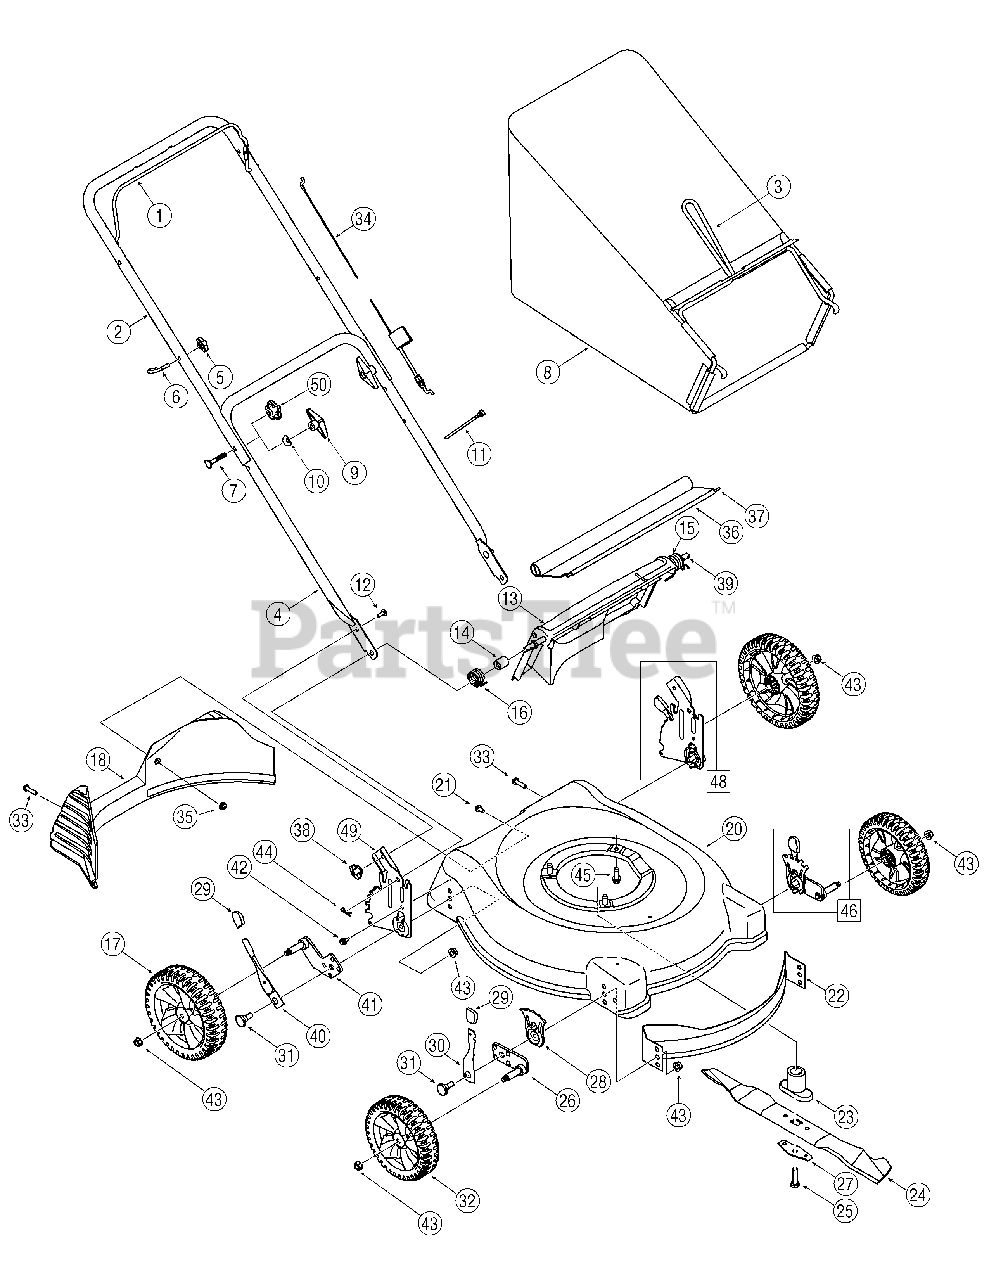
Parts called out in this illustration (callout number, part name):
5	Knob 1/4-20
6	Rope Guide Bolt
7	Curved Carriage Bolt 5/16-18 x 2.00
8	Generic Grasscatcher Bag Black
8	Grasscatcher Bag YM
9	Knob 5/16-18
10	Saddle Washer
11	Cable Tie
12	Carriage Bolt 1/4-20 x 75 Gr 1
13	RB Chute Door
14	Spacer .390 x .810 x .950
15	LH Torsion Spring
16	RH Torsion Spring
17	Wheel Ass'y 8 x 1.8 Spoke Bar Grey
18	RR Baffle
21	Mach. Scr. Pan Phil. 1/4-20 x .50
22	Front Baffle 21"
23	Blade Adapter
24	21" Blade (w/star)
24	21" Mulching Blade (w/star)
25	Hex Bolt 3/8-24 x 2.5" Lg. Gr. 8
26	Pivot Bar RH
27	Blade Bell Support
28	Height Adjuster Plate
29	Knob
30	Spring Lever Ass’y (w/knob)
31	Shoulder Screw .50 Dia.
32	Wheel Ass'y 7 x 1.8 Spoke Bar Grey
33	Hex. L-Scr. 1/4-15 x 1.5
34	Control Cable 53.0" Lg. Snap-on
35	Flanged Locknut 1/4-20 Gr. F Nylon
36	Rear Flap
37	Wire
38	Wingnut 1/4-20
39	Pivot Rod
40	Spring Lever SP (w/knob)
40	Knob
41	Pivot Bar RH SP
42	Hex HD. TT Tap screw. 1/4-20 x 5/8
43	Flange Locknut 3/8-16
44	Int. Cotter Pin 5/16 DIA
45	Hex Wash HD Tap screw 3/8-16 x .88
46	Height Adj. Ass’y LH (w/knob)
47	Height Adj. Ass’y RH (w/knob)
48	LH Rear Height Adj. Ass’y Complete
48	RH Rear Height Adj. Ass’y Complete
49	LH Height Adj. Brkt
49	RH Height Adj. Brkt
50	Knob - Star 5/16-18
